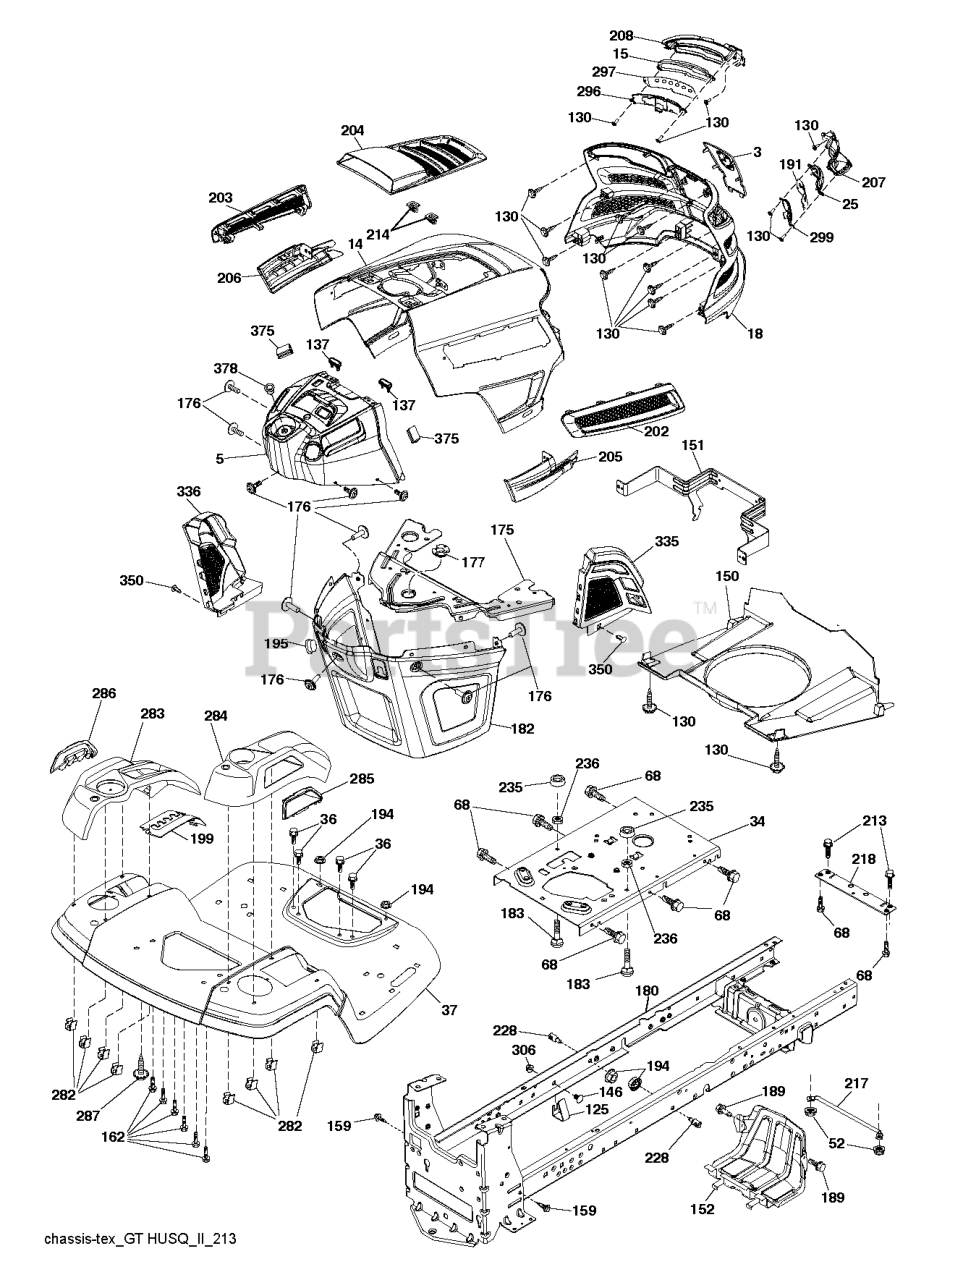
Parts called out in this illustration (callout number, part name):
3	APPLIQUE.SUBASM.GT.HUSQ.II
5	DASHBOARD TEX;GT2;UPPER S_M_
14	HOOD.ASM.HUSQVARNA.GT.TEX.ORAN
15	LED LIGHT.LH
18	GRILLE SUBASM.GT.II.LOW.HDLGHT
25	LENS.RH
34	PLATE.ENGINE.WELDED.CHASSIS
36	SCREW 5/16"
37	FENDER.TLT.PDL.CNTRL.W/CPH.ORG
52	LOCKNUT
68	SCR 5/16-18 X 1/2 SELFTAP ZN
125	CLIP.FUEL.LINE
130	SCREW.#10 X 0.750.BOS
137	BUMPER DASH
146	BOLT.RDHD.SHT.SQNK.3/8-16X5/8
150	AIR DUCT.GTV2(1.66"RING HEIGHT
151	BRACKET.PIVOT.HOOD.GT.HUSQ.II
152	SHIELD.BROWNING.PNT.GT.V2
159	SCREW, 3/8-16X3/4
162	SCREW.HI-LO.CONSOLE
175	PLATE.PNT.CROSSMEMBER.HUSQ/PRE
176	SCREW.#10-24X5/8.RN.QU
177	BUSHING STEERING
180	CHASSIS
182	DASH.LOWER.COMMON.12V.ADAPTOR
183	BOLT.5/16-18X1-1/4 FULL THD
189	SCREW
191	INSERT INFLECT.RH
194	NUT LOCK HEX FLANGE 5/16-18
195	PLUG.HOLE.DASH.LOWER.12V.BLK
199	PLATE.DECK.LIFT.HUSQ.LT
202	VENT.SIDE.RH.GT.HUSQ.II.
203	VENT.SIDE.LH.GT.HUSQ.II.498
204	VENT.TOP.HUSQ.GT2
205	SIDE.TRIM.RH.GT.HUSQ.II
206	SIDE.TRIM.LH.GT.HUSQ.II.GRAY
207	BEZEL GT2 LED RH W/ LOWER.ATT
208	BEZEL GT2 LED LH W/ LOWER ATT
213	BOLT
214	CLIP.RETAINER.TINNER.
217	ROD.PIVOT.HOOD
218	X-PIECE.HOOD.STOP.NON/
228	STUD.FASTNER.W/ANTI-ROTATE
235	SPACER FENDER
236	NUT.CENTERLOCK.5/16-
282	CLIP.RETAINER.CONSOLE.LT.HUSQ
283	CONSOLE.DECK.LIFT.R.SDFL.HUSQ
284	CONCOLE.CNTRL.PDL.HUSQ.LT.498
285	CONSOLE INSERT RH
286	CONSOLE.INSRT.LH.HUSQ.LT.BLACK
287	SCREW 1/4X20
296	LED LIGHT.LH
297	INSERT REFECT LH
299	LED LIGHT.RH
306	NUT LOCK FLG 3/8-16 UNC
335	COVER.LOWER.DASH.RH.BLACK
336	COVER-LH.LOWER.DASH.GT2.BLACK
350	CLIP.X-MAS.TREE
375	BUMPER CLIP-ON. DASH 1"
378	BUSHING FLANGE; PLASTIC
